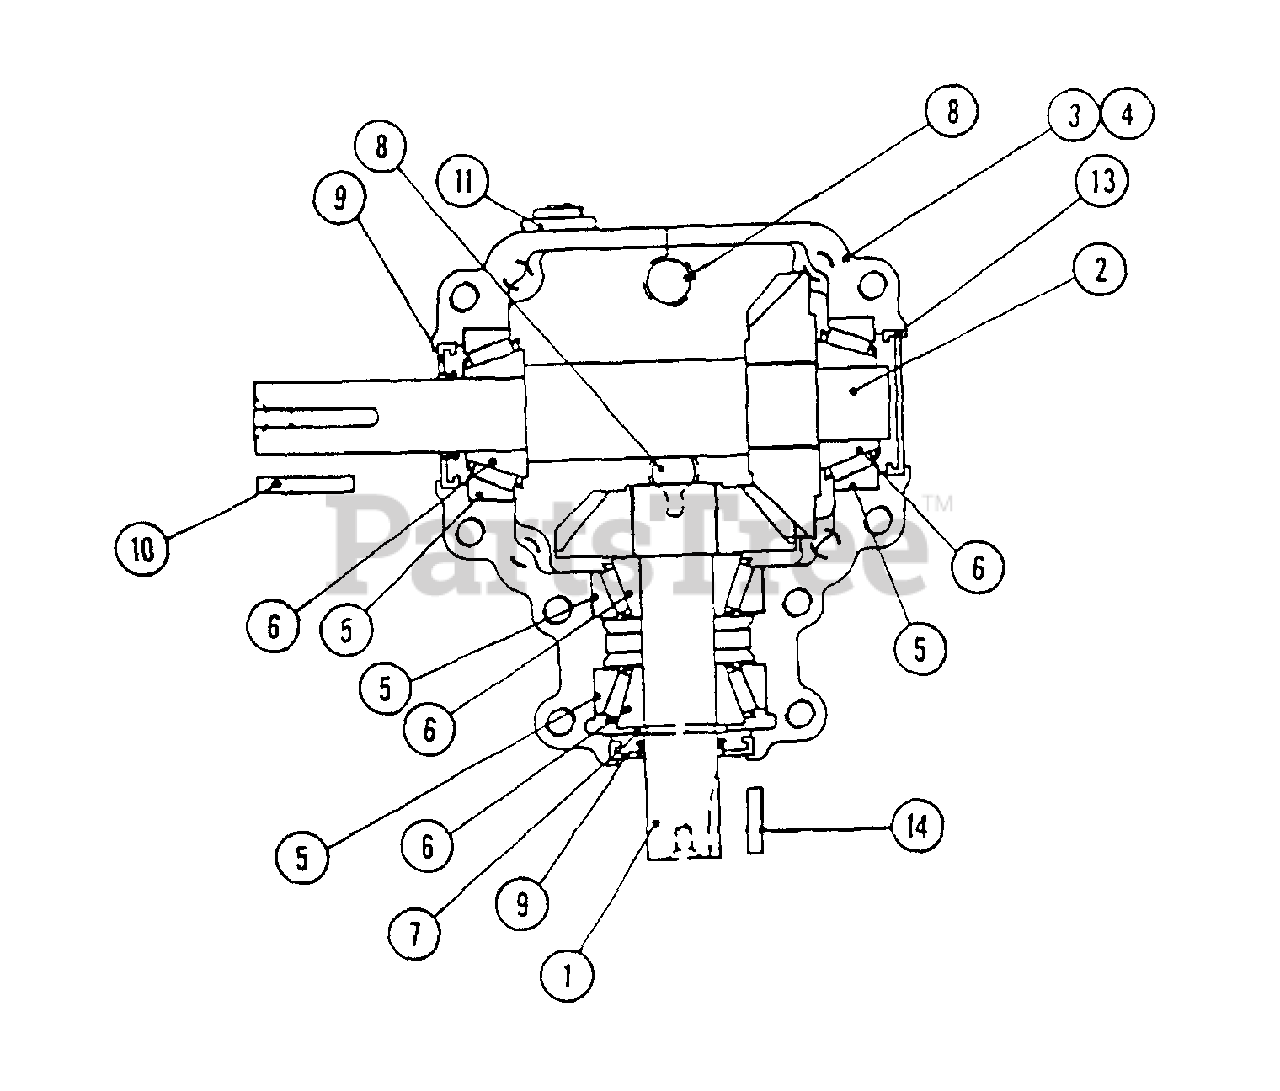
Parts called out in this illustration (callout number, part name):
1	SHAFT - pinion, with gear
2	SHAFT - cross, with gear
3	HOUSING - with tapped holes
5	CUP - bearing
6	CONE - bearing
7	RING - retaining
8	PLUG - pipe 1/4"
10	KEY - 3/16" x 1" input shaft
11	PIPE - vent
13	CAP - end
14	KEY - 3/16" x 5/8" output shaft
